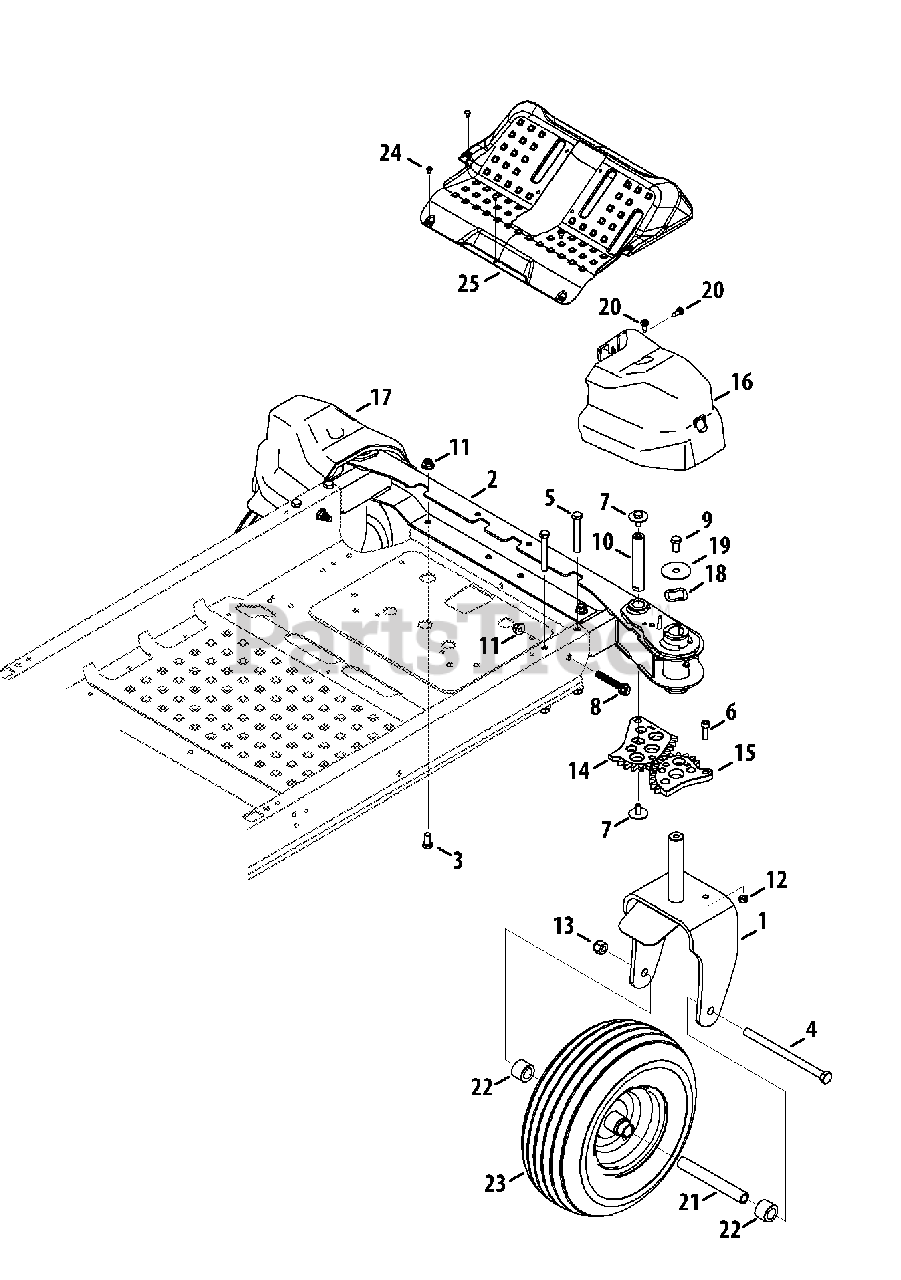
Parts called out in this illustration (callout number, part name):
1	Caster Wheel Bracket
2	Front Axle
3	Hex Cap Screw, 3/8-16 x .75
4	Bolt, 1/2-20 x 7.25
5	Screw, 3/8-16 x 2.75
6	Socket Head Screw, 5/16-18 x 1.00
7	Hex Cap Screw, 5/16-18 x .75
8	Hex Flange Screw, 3/8-16 x 2.25
9	Hex Screw, 3/8-16 x .75
10	Pivot Gear Steering Shaft
11	Flange Lock Nut, 3/8-16
12	Hex Lock Nut, 5/16-18
13	Hex Lock Nut, 1/2-20
14	12-Tooth Variable Gear
15	13-Tooth Variable Spur Gear
16	Axle Cover, RH
17	Axle Cover, LH
18	Wave Washer, 1.25 x 1.00 x .300
19	Flat Washer, .406 x 1.92 x .060
20	Shoulder Screw, 1/4-20
21	Spacer, .51 ID x .75 OD x 5.825
22	Hub, .76 x 1.23 x .92 LG
23	Wheel Assembly, 13 x 5-6
24	Self Tapping Screw, 1/4-20 x .50
25	Floor Board
